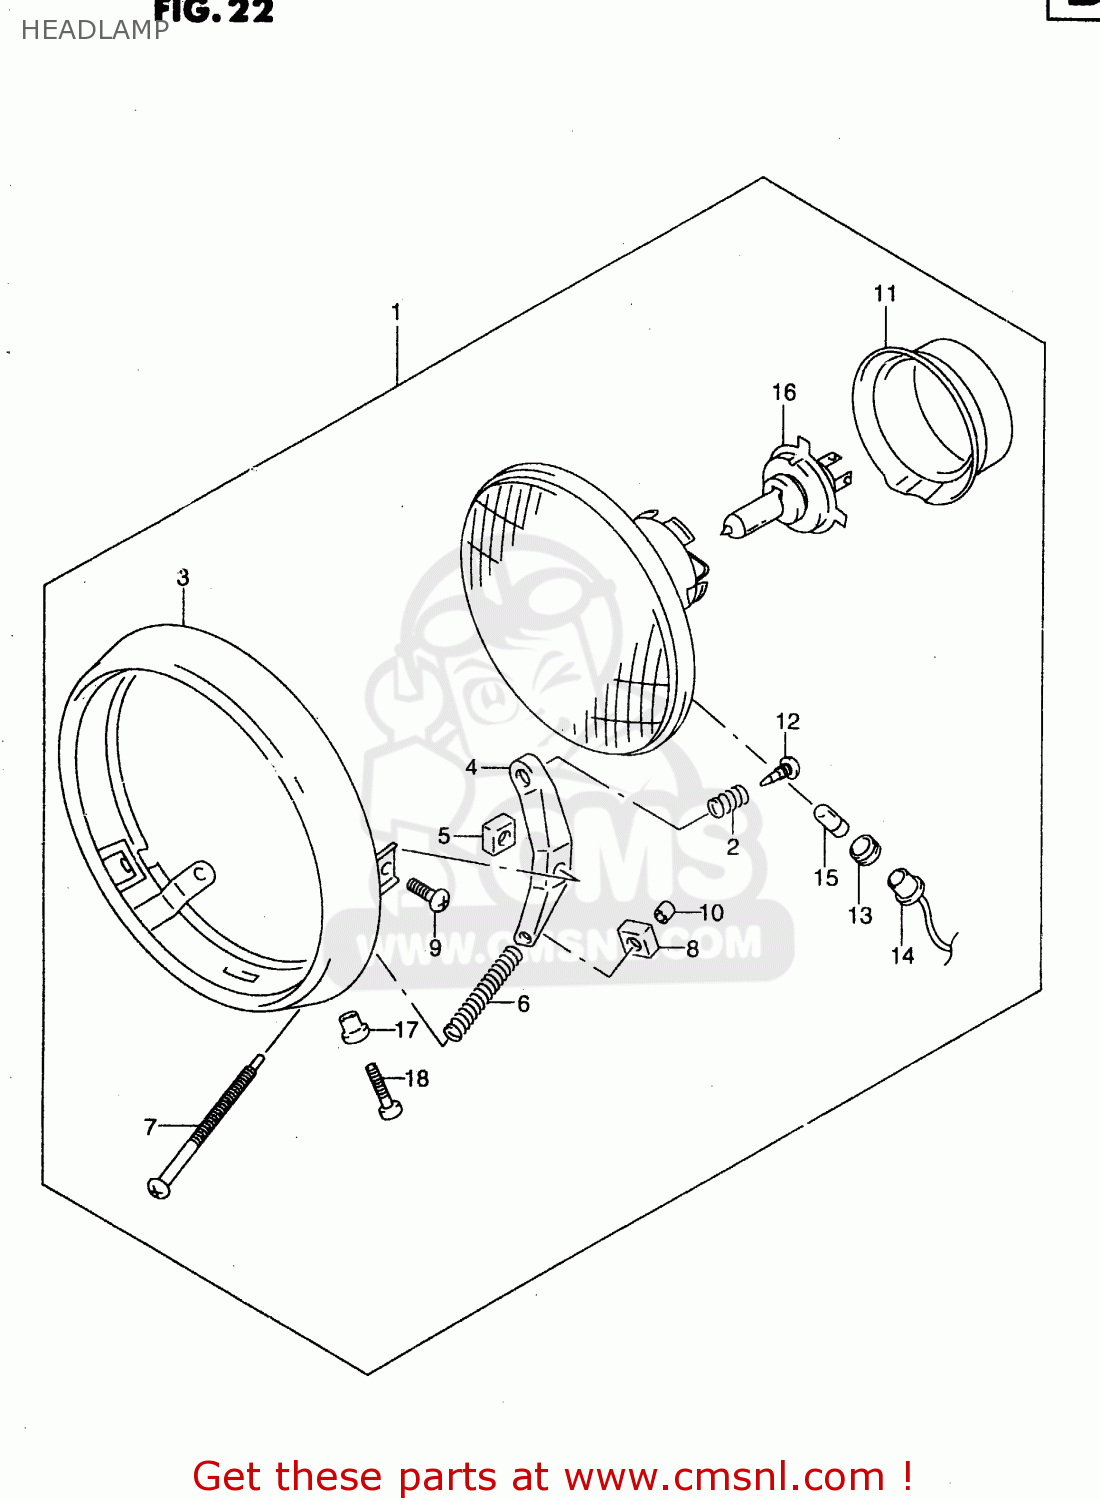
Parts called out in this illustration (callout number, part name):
1	HEADLAMP ASSY
2	SPRING
3	RIM,HEAD LAMP
4	STAY
5	NUT
6	SPRING
7	ADJUSTER SCREW
8	NUT,HEADLAMP ADJUST
9	SCREW
10	CAP,SCREW
11	COVER,SOCKET
12	SCREW
13	JOINT,RUBBER
14	CORD,POSITION
15	BULB(12V4W)
16	BULB(12V60/55W,H4)
17	SPACER,HEADLAMP
18	SCREW
